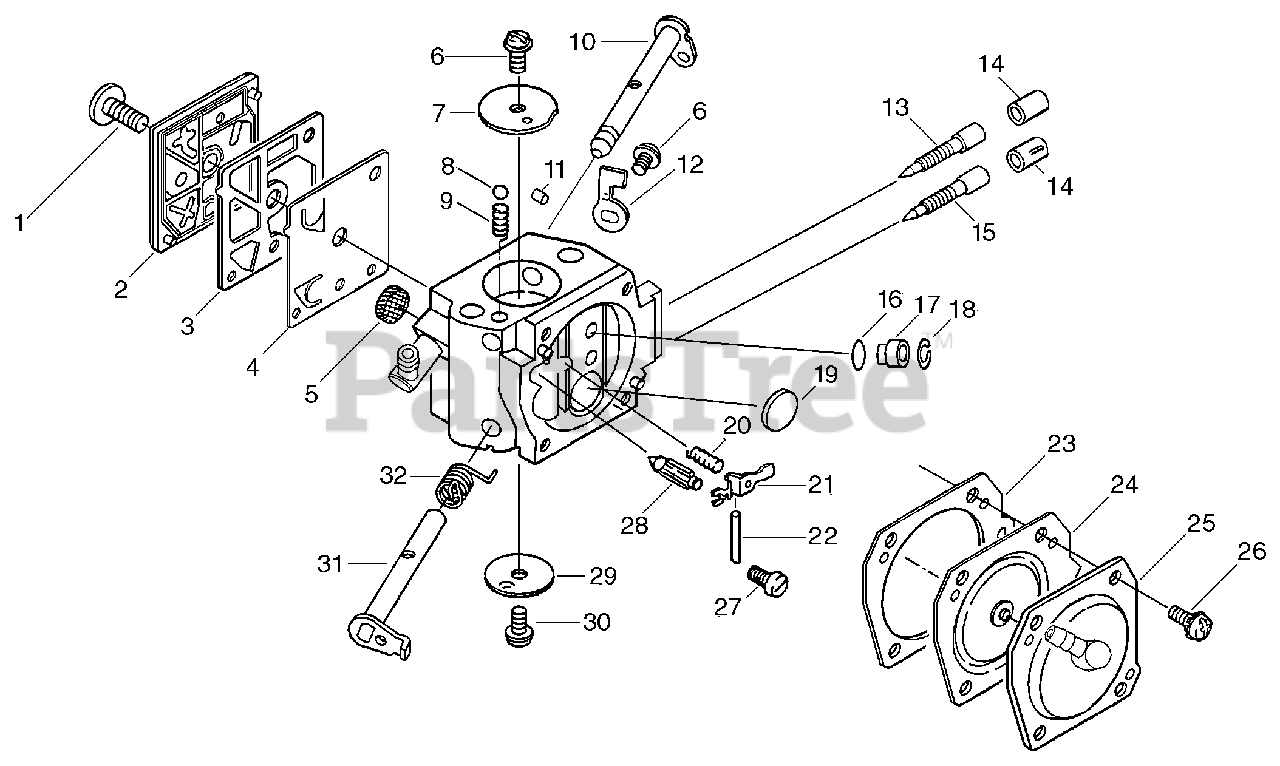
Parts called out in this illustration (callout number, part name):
2	COVER, FUEL PUMP
3	GASKET, FUEL PUMP
4	DIAPHRAGM, FUEL PUMP
5	SCREEN, FUEL INLET
7	VALVE, CHOKE
8	BALL, CHOKE FRICTION
10	LEVER, CHOKE
11	PLUG, FRICTION
12	STOP, THROTTLE
13	NEEDLE, HIGH SPEED
14	CAP, LIMITER
15	NEEDLE, MIXTURE
16	O-RING
17	JET
18	RING, RETAINING
19	PLUG, WELCH
20	SPRING, METERING LEVER
21	LEVER, METERING
22	PIN, METERING LEVER
23	GASKET, METERING DIAPHRAGM
24	DIAPHRAGM, METERING
25	COVER, METERING DIAPHRAGM
27	SCREW, METERING LEVER PIN
28	VALVE, INLET NEEDLE
29	VALVE, THROTTLE
31	SHAFT, THROTTLE
32	SPRING, THROTTLE RETURN
